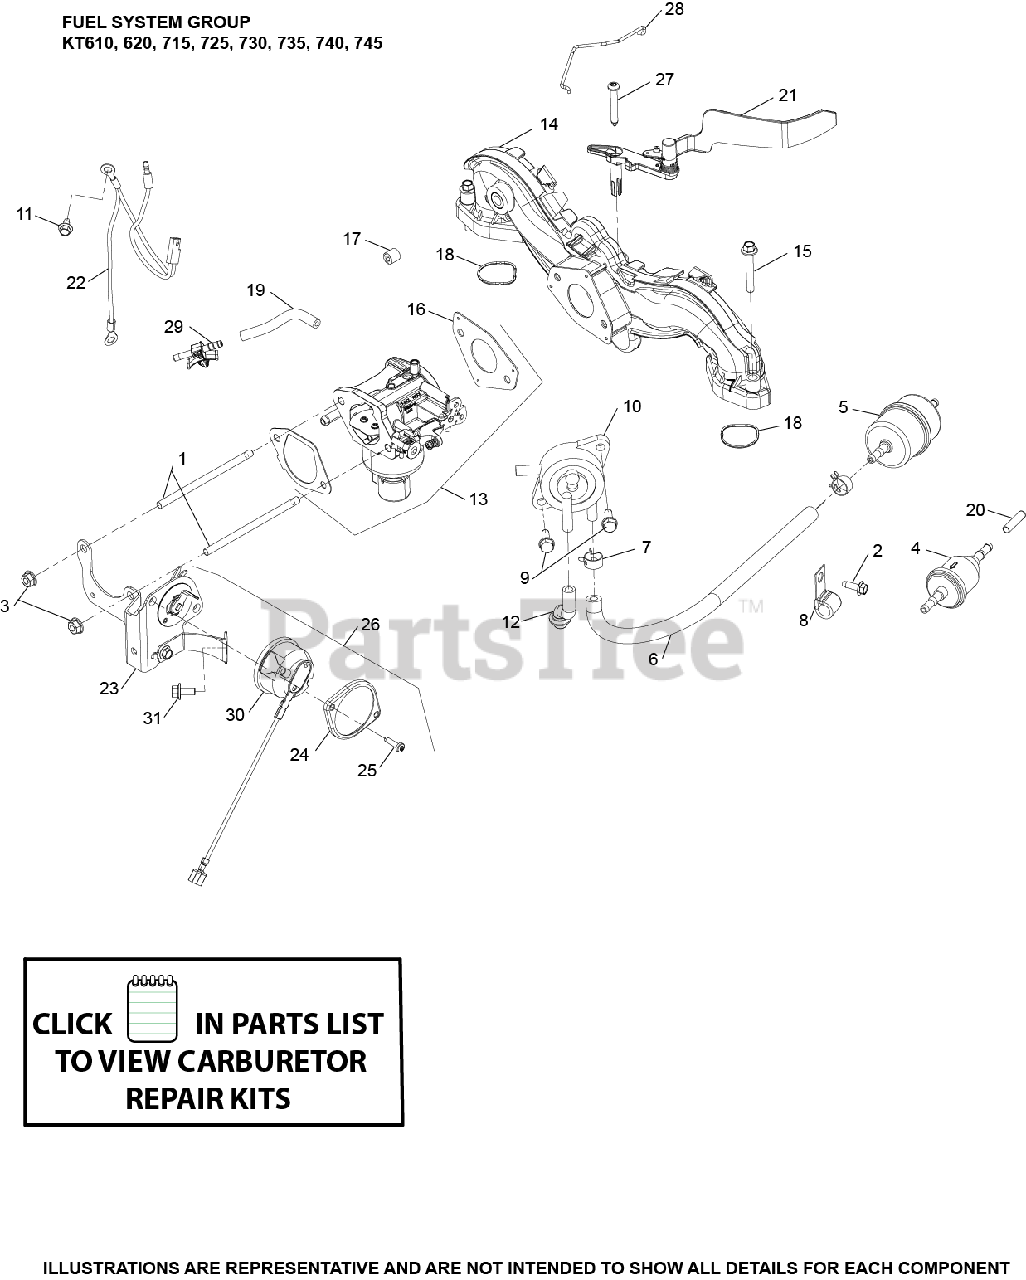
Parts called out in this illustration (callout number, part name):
3	NUT, FLG M6X1.0
5	FILTER, FUEL
6	HOSE,LW PERM.FUEL 24.00"-USE 25 111 81-S
7	CLAMP SPRING HOSE
8	CLIP, CABLE
9	SCREW, TAP M6X1.7X18
10	PUMP, FUEL (PULSE)
11	SCREW, THREAD FORMING
13	KIT, CARBURETOR COMPLETE
14	KIT, INTAKE MANIFOLD USE 24 164 266-S
15	SCREW, FLG M6X1.0X40
16	GASKET, CARBURETOR
17	PLUG, CTSK PIPE 1/8"
18	O-RING, INTAKE PORT
